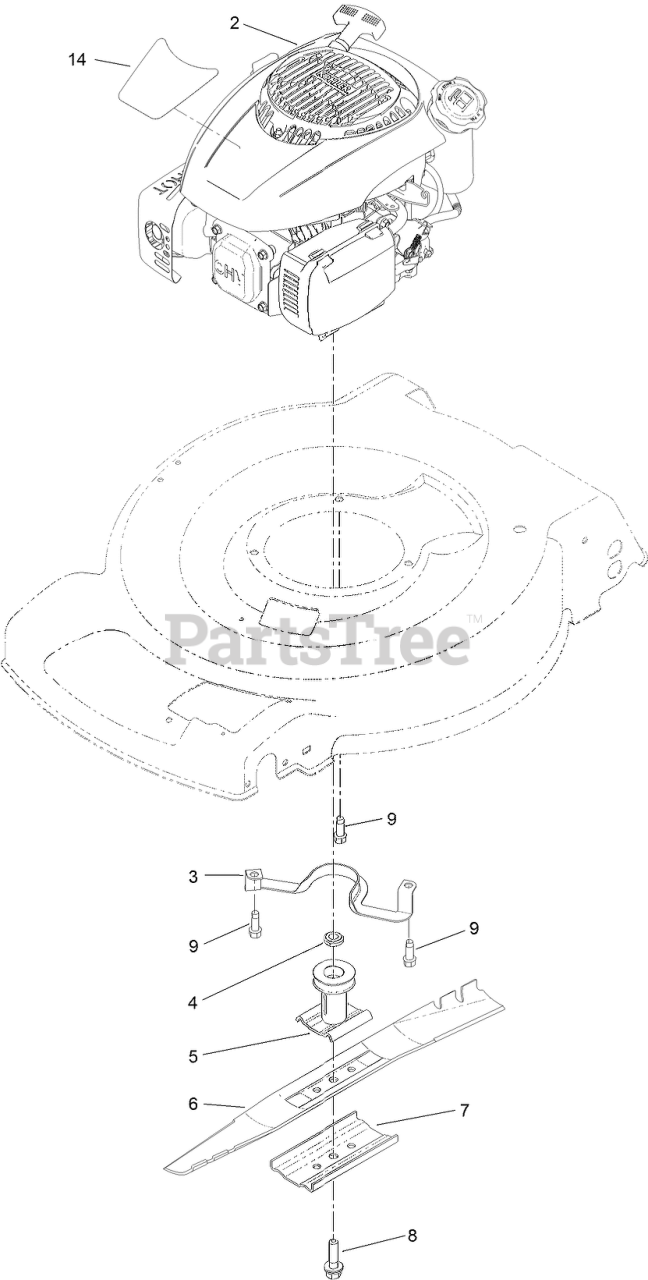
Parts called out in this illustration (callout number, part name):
3	Guide-Belt
4	Spacer-Driver
5	DRIVER-BLADE
6	BLADE-22 INCH
7	SUPPORT-BLADE
8	BOLT-BLADE
9	SCREW-TAPTITE
14	DECAL-SHROUD
